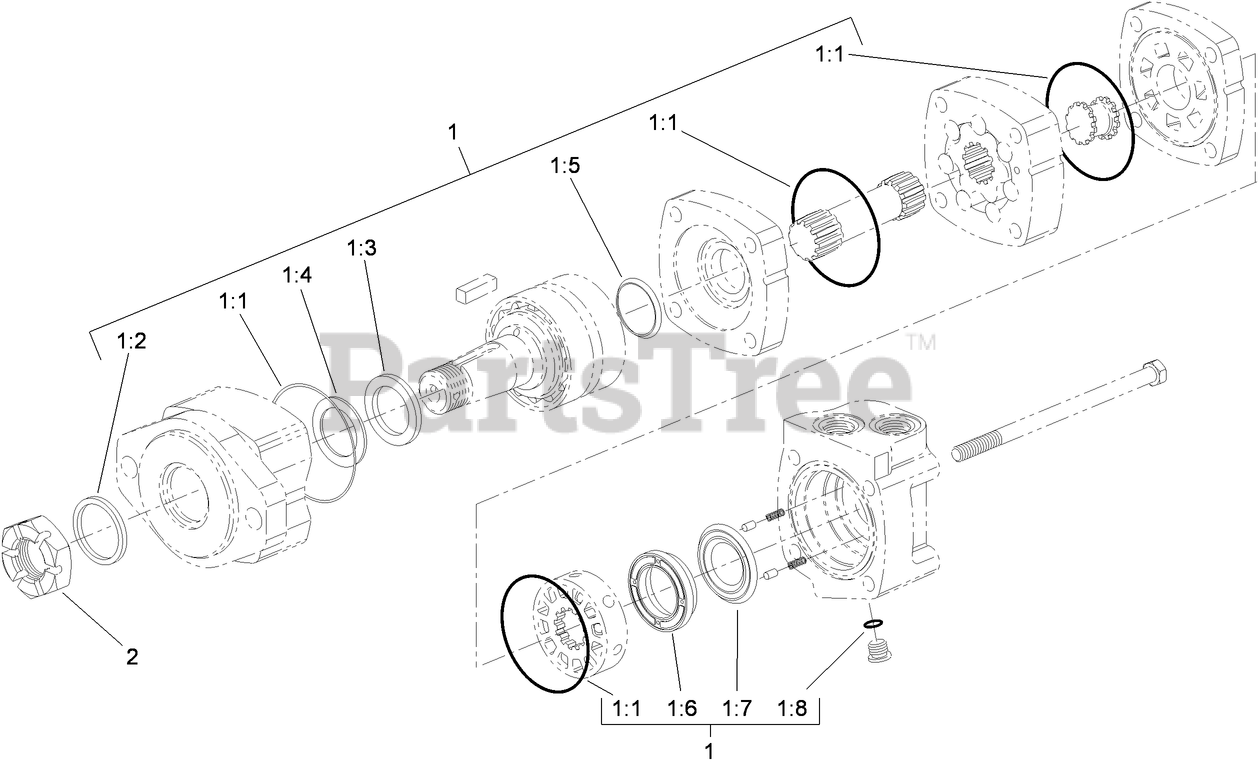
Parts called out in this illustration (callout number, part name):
1	SEAL KIT
1:1	RING-RETAINING
1:2	Seal-Exclusion, Shaft
1:3	Seal-Shaft
1:4	Ring-Back-Up
1:5	Seal-Face, Shaft
1:6	Seal-Face, Inner
1:7	Seal-Face, Outer
1:8	RING-RETAINING
